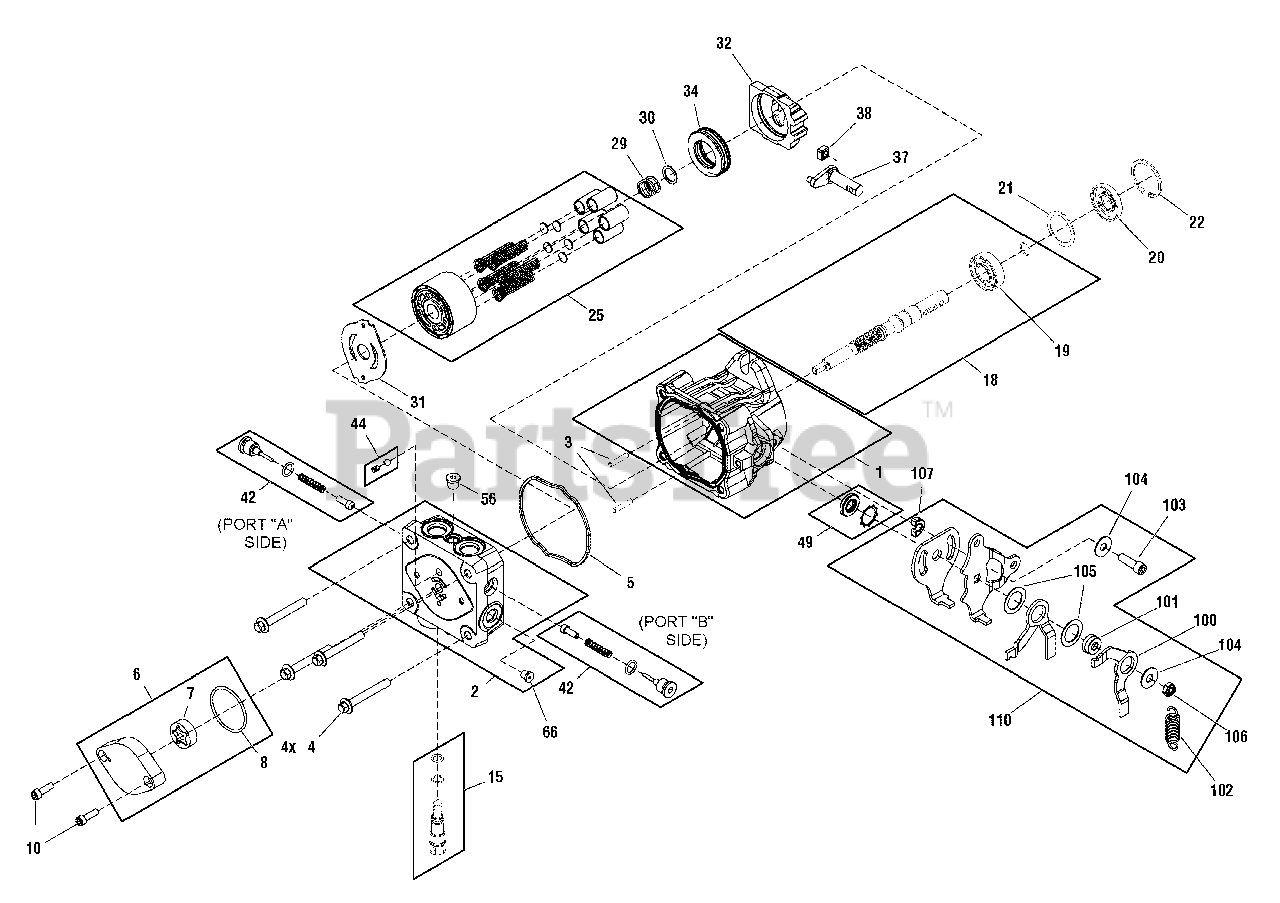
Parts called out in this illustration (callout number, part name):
1	Housing Kit
2	End Cap Kit (W/ Poppets, Standard Charge) (Includes Ref. Nos. 66)
3	Straight Headless Pin
4	Hex Flange Bolt M8-1.25 X 60mm LG
5	Housing O-Ring
6	Charge Pump Kit (STD) (Includes Ref. Nos. 7 & 8)
7	STD Gerotor Assy (11 cu. In/rev D-Drive) (Not a Serviceable Part)
8	O-Ring (Not a Serviceable Part)
10	Socket Head Screw M6 x 1.0-20mm Lg (STD Charge)
15	Bypass Valve Kit (Blank)
18	Pump Shaft Kit (Blind 15mm Keyway W/ Std Charge) (Includes Ref. Nos. 19)
19	Ball Bearing 17 x 40 x 12 (Not a Serviceable Part)
20	Lip Seal 17 x 40 x 7 PTC
22	Retaining Ring
25	Cylinder Block Kit
29	Block Spring
30	Block Thrust Washer
31	Valve Plate (Steel N-Tec:Black)
32	Swashplate
34	Ball Thrust Bearing
37	Trunnion Arm, Tapered Square
38	Slot Guide
42	Check Valve Kit (0.031"Orifice)
44	Charge Relief Valve Kit (1/4" Plastic Ball & Spring)
49	Trunnion Seal / Retainer Kit
56	Straight Thread Plug
66	5/16" SAE Plug (Not a Serviceable Part)
94	Arm, Control
98	Arm, Retrun
99	Arm, Retrun Scissor Inner
100	Arm, Retrun Scissor Outer
101	Spacer RTN (Not a Serviceable Part)
102	Spring, Extension (Not a Serviceable Part)
103	Screw, 5/16 x .875 (Patch) (Not a Serviceable Part)
104	Washer .34 x .88 x .06 (Not a Serviceable Part)
105	Washer, Nylon (Not a Serviceable Part)
106	Nut, Hex Lock 5/16-24 UNF (Not a Serviceable Part)
107	Spacer (Not a Serviceable Part)
110	Kit, RTN, STD (Includes Ref. Nos. 94, 98, 100, 101, 102, 103, 104, 104, 105, 106 & 107)
111	Overhaul Seal Kit
